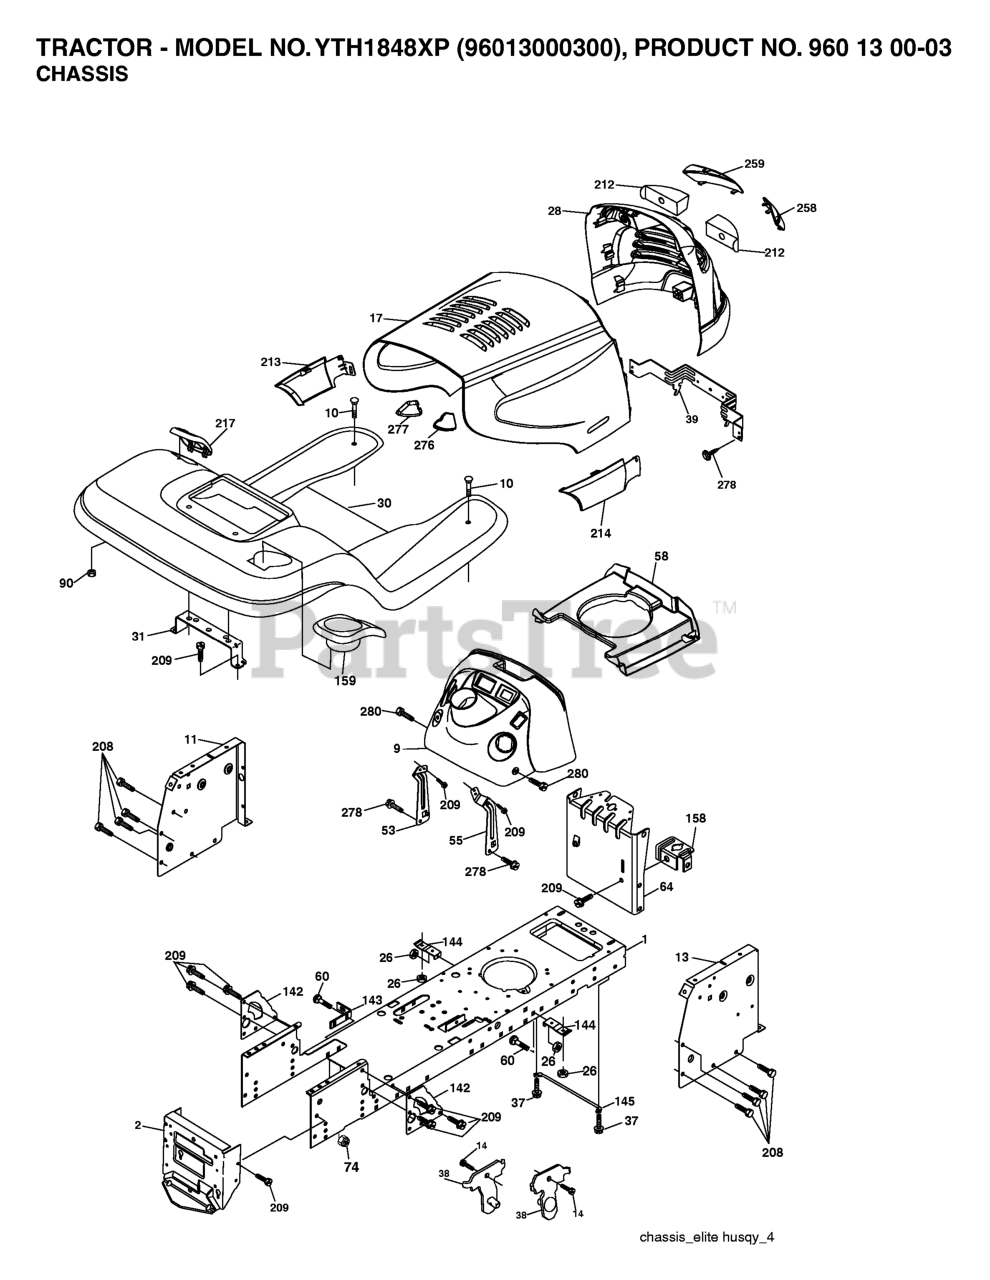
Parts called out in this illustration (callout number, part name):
1	CHASSIS STAMPING
2	DRAWBAR, 12GA
9	DASH
10	BOLT D
11	PANEL.DASH.LH.LTX
13	PANEL DASH RH
20	PLATE BATTERY
26	NUT
30	FENDER
31	BRACKET.SUPPORT.FENDER
37	Screw 5/16-18 x 1/2 Hex, Self Tapping 5/16-18 x 1/2
38	BRACKET.ASM.PIVOT.MOWER.REAR
39	BRACKET PIVOT LASER
60	Bolt - Rd. Hd. Sq. Neckiage 3/8 16 x 3/4
64	DASH LOWER
90	NUT.PUSH.3/16
142	PLATE REINFORCEMENT
143	BRACKET, SWAYBAR CHASSIS
144	BRKT, FOOT REST
145	ROD PIVOT CHASSIS/HOOD
158	BRACKET PARKING BRAKE
159	CUPHOLDER
208	SCREW 3/8-16X1/2
209	SCREW, 3/8-16X3/4
217	CONSOLE FUEL WINDOW
278	SCREW
280	SCREW 3/8-16X1
